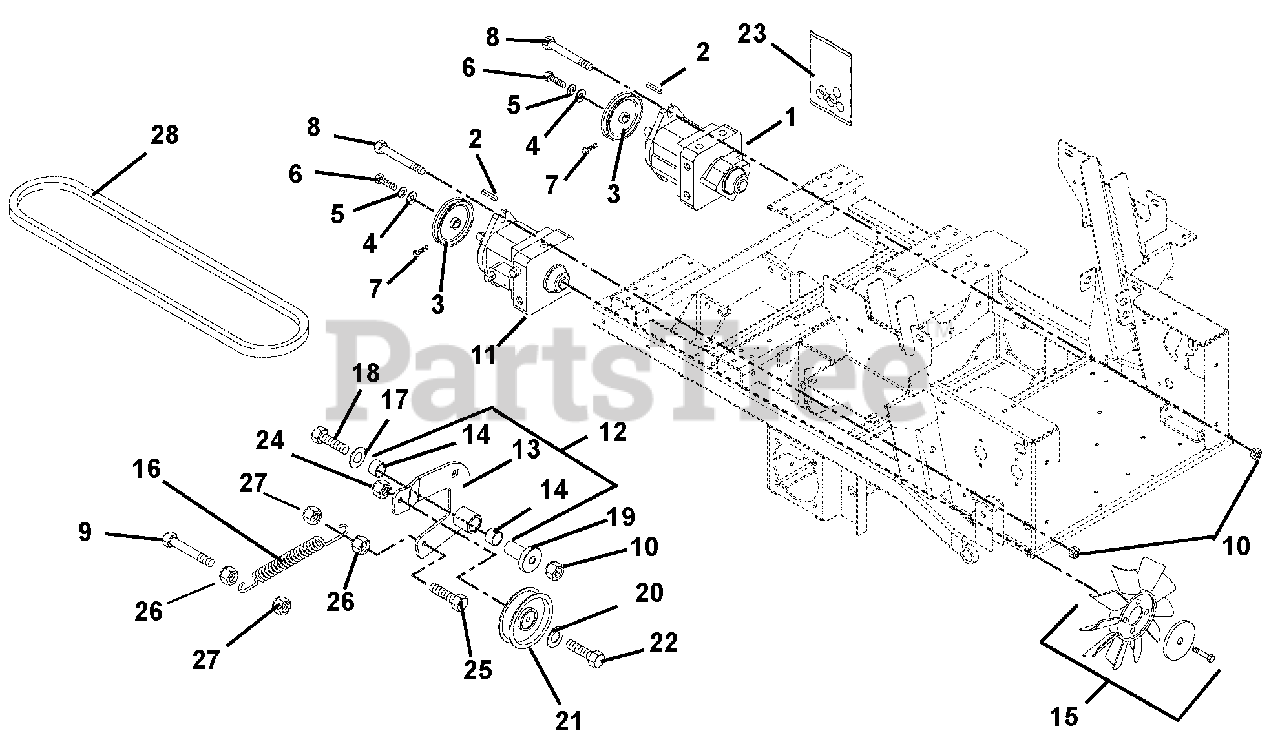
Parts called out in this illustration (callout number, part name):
1	PUMP, HYD. (RTN) W/AUX
2	KEY, SQ 5 X 5 X 30MM PLAIN
3	SHEAVE, POLY V .671 X 4.125
4	WASHER, PUMP .28X1.25X.50
5	@WSHR-LK .25X.062 REG YWZC
6	@BLT-HEX M6-1X16 YWZC
7	SCR-SKH .25-20 X .50 PH & OIL
8	@BLT-HEX .50-13X1.50 GR5 YWZC
9	@BLT-HEX .31-18X2.50 GR5 YWZC
10	@NUT-LK-TOP-FLG .50-13 YWZC
11	PUMP, HYD. (RTN)
12	ASSEMBLY, IDLER ARM
13	WMT, IDLER ARM
14	BRG, 1.00 X 1.12 X .75
15	FAN KIT, HYDROGEAR 70618
16	SG-TENS .135X.69X5.75 WLD 150
17	@WSHR-FL-STL.563X1.38X.109YWZC
18	@BLT-HEX .50-13X3.50 GR5 YWZC
19	BEARING, PEDESTAL
20	@WSHR-FL-STL.406X.812X.065 YWZ
21	IDLER-FLAT 4.00 X .38 NWHAMSHR
22	BLT-HEX .38-16X1.625
23	KIT, PUMP SEAL (BDP-21L)
24	@NUT-LK-TOP-FLG .38-16 YWZC
25	@BLT-HEX .31-18X1.25 GR5 YWZC
26	@NUT-HEX .31-18 YWZC
27	@NUT-LK-TOP-FLG .31-18 YWZC
28	POLY V-BELT, K-5 RIBS
